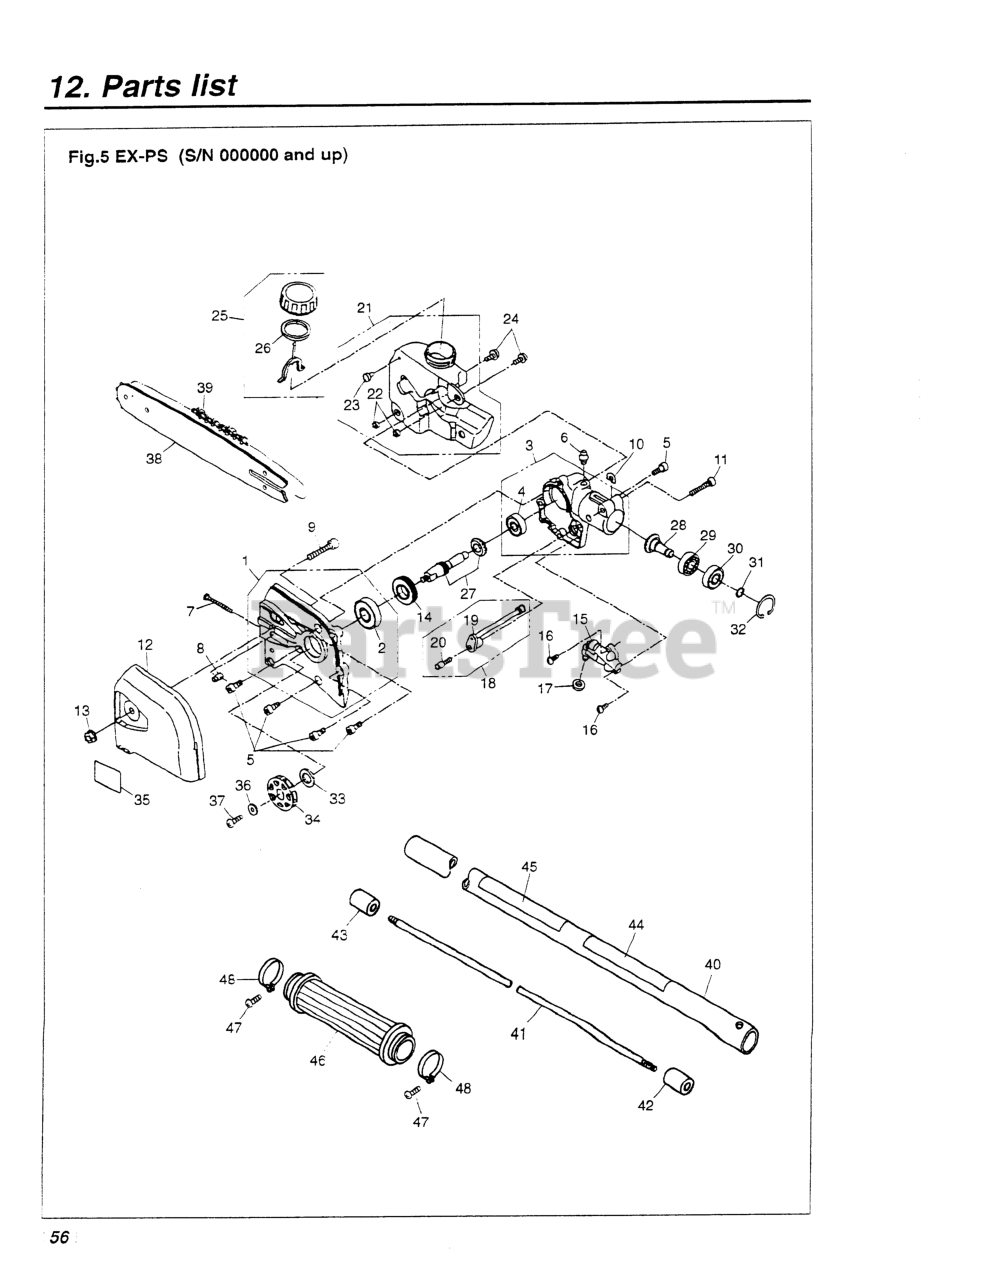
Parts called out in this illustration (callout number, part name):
2	BEARING
3	GEARCASE COMP (RIGHT)
5	BOLT, M5 x 12
6	FITTING, GREASE
7	SCREW
8	NUT
9	BOLT, M6 x 30
10	SHIM
12	COVER, CHAIN
13	NUT
14	GEAR, WORM
15	PUMP ASSY, OIL
16	SCREW, M4 x 10
17	GASKET
18	PIPE ASSY, OIL
19	PIPE, OIL
20	FILTER
21	TANK ASSY, OIL
22	COLLAR
23	VALVE
24	SCREW, M5 X 12
25	CAP ASSY, OIL
26	GASKET, OIL CAP
27	SHAFT, GEAR
28	GEAR, BEVEL
29	BEARING (RPLS T3403-13530)
31	RING, SNAP (RPLS T3300-13330)
32	RING, SNAP, M24 x 1.2
33	COLLAR
34	SPROCKET
35	LABEL (PSZ2500)
36	WASHER
37	SCREW
39	12
40	PIPE COMPLETE
41	SHAFT
42	JOINT, SHAFT (RPLS -12240)
43	SPACER
44	PLATE, NAME (PS-EX)
45	PLATE, CAUTION
46	GRIP
48	SCREW (RPLS 00260- )
